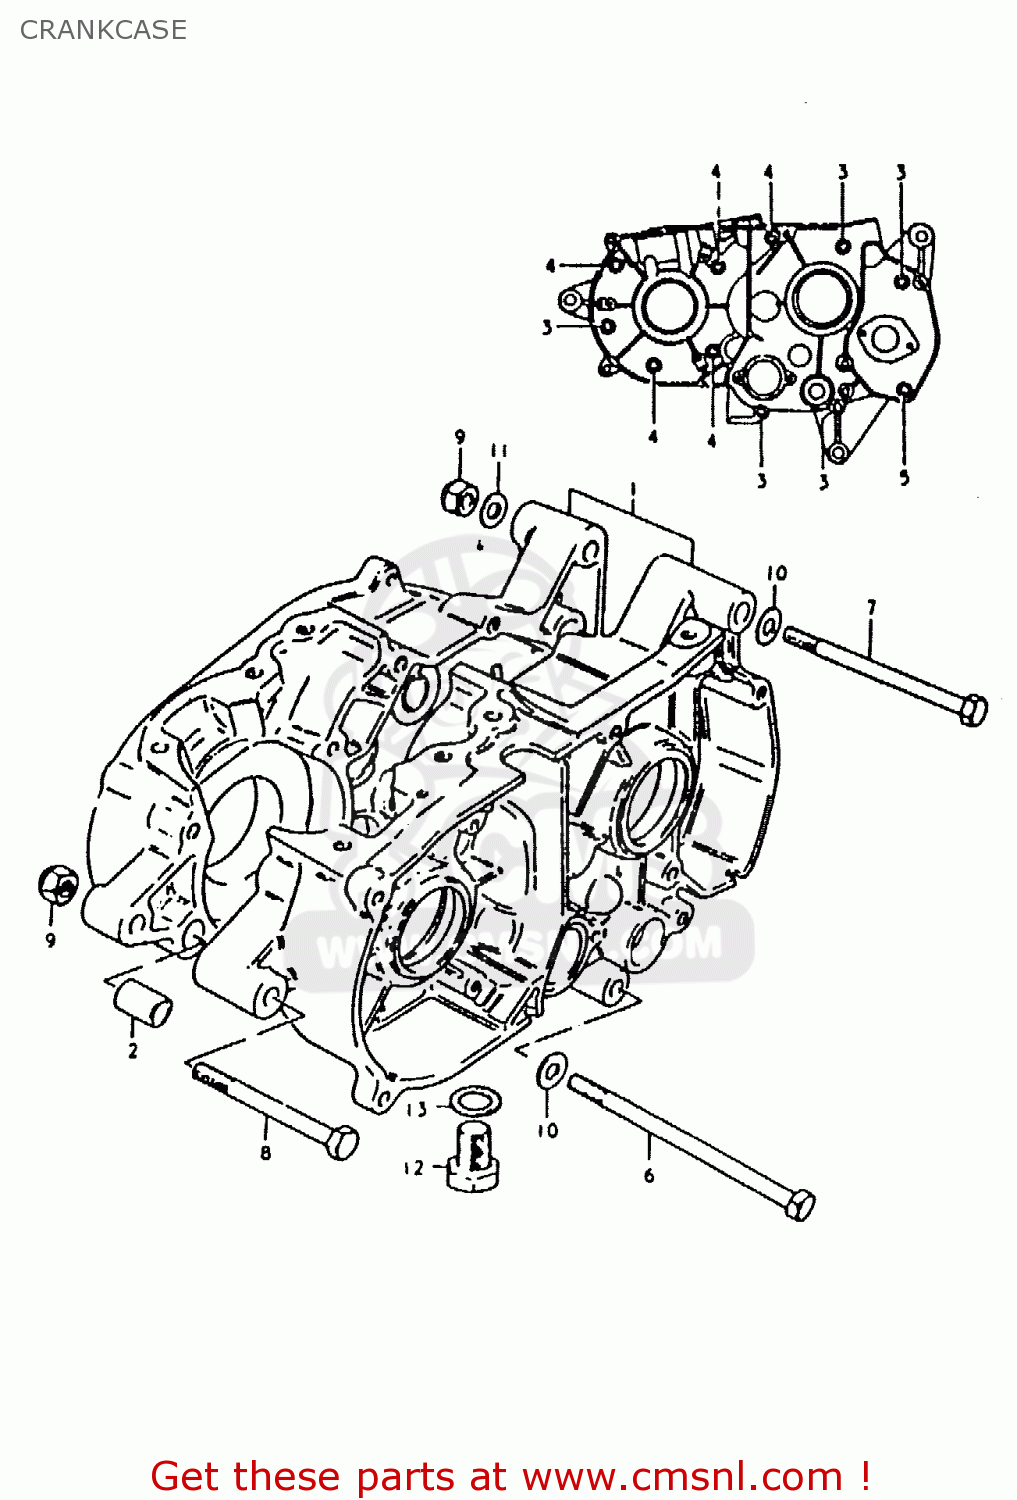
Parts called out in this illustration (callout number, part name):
1	CRANKCASE SET
2	PIN
3	SCREW (6X45)
4	SCREW (6X35)
5	SCREW
6	BOLT
7	BOLT
8	BOLT 8X75
9	NUT
10	WASHER
11	WASHER
12	BOLT 10X20
13	GASKET(10X14X3.6) (NAS)
